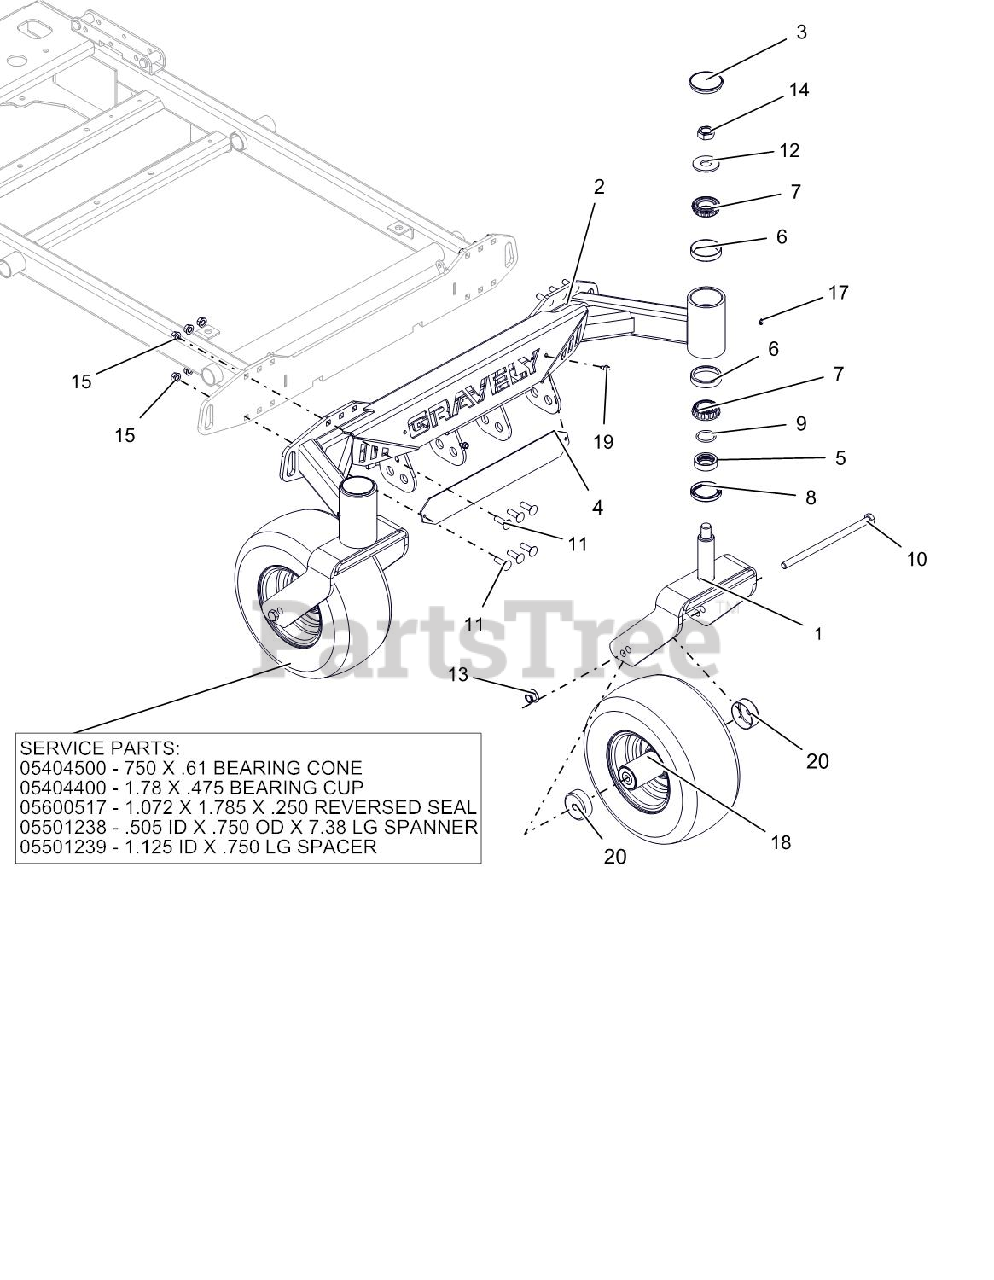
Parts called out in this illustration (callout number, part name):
1	CASTER FORK WMT - RED
2	WLDMT, FRONT 60 AXLE
3	CAP, DUST
4	BACKER, NAMEPLATE
5	SPACER, FRONT CASTER FORK
6	BRG-CUP 2.328X.465
7	BRG-CONE 1.25X.66
8	SEAL, OIL 1.75 X 2.332 X .312
10	BLT-HEX .50-13X9.00 GR5 YWZC
11	BLT-RDHDSQNK .38-16X1.25 G5YZ
12	WSHR-FL-STL.812X2.00X.148YWZC
13	NUT-LK-NYL-FLG .50-13 YWZC
14	NUT-JAM TOPLK .75-16 YWZC
15	NUT-LK-TOP-FLG .38-16 YWZC
17	FTG, .25-28 FLUSH MNT GREASE
18	ASM, WHL/TIRE 13X6.50-6 SEMI
19	SCR-TAP .25-20X.50 HWH TR YWZ
20	SHIELD, WHEEL BEARING
21	BRG-CONE .750X.61
22	BRG-CUP 1.781X.475
23	SEAL, 1.125 X 1.781 X .469
24	SPANNER,.505ID X.750OD X7.38LG
25	SPACER, 1.125 ID X .750 LG
